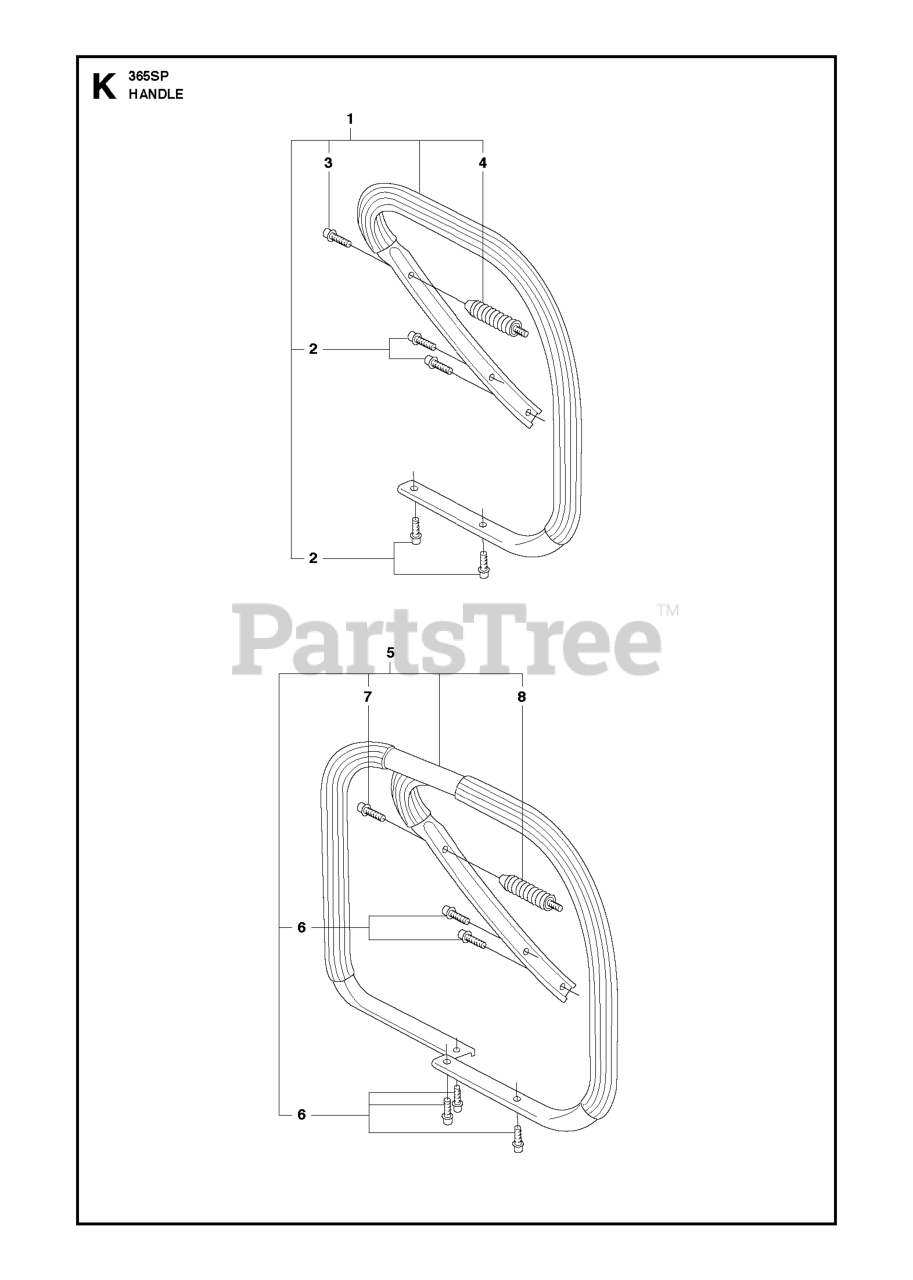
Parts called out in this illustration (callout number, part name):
1	FRONT HANDLE
2	SCREW
4	VIBRATION ABSORBER
4	ANTIVIBE MOUNT
5	FRONT HANDLE/WRAP
6	SCREW
8	ANTIVIBE MOUNT
